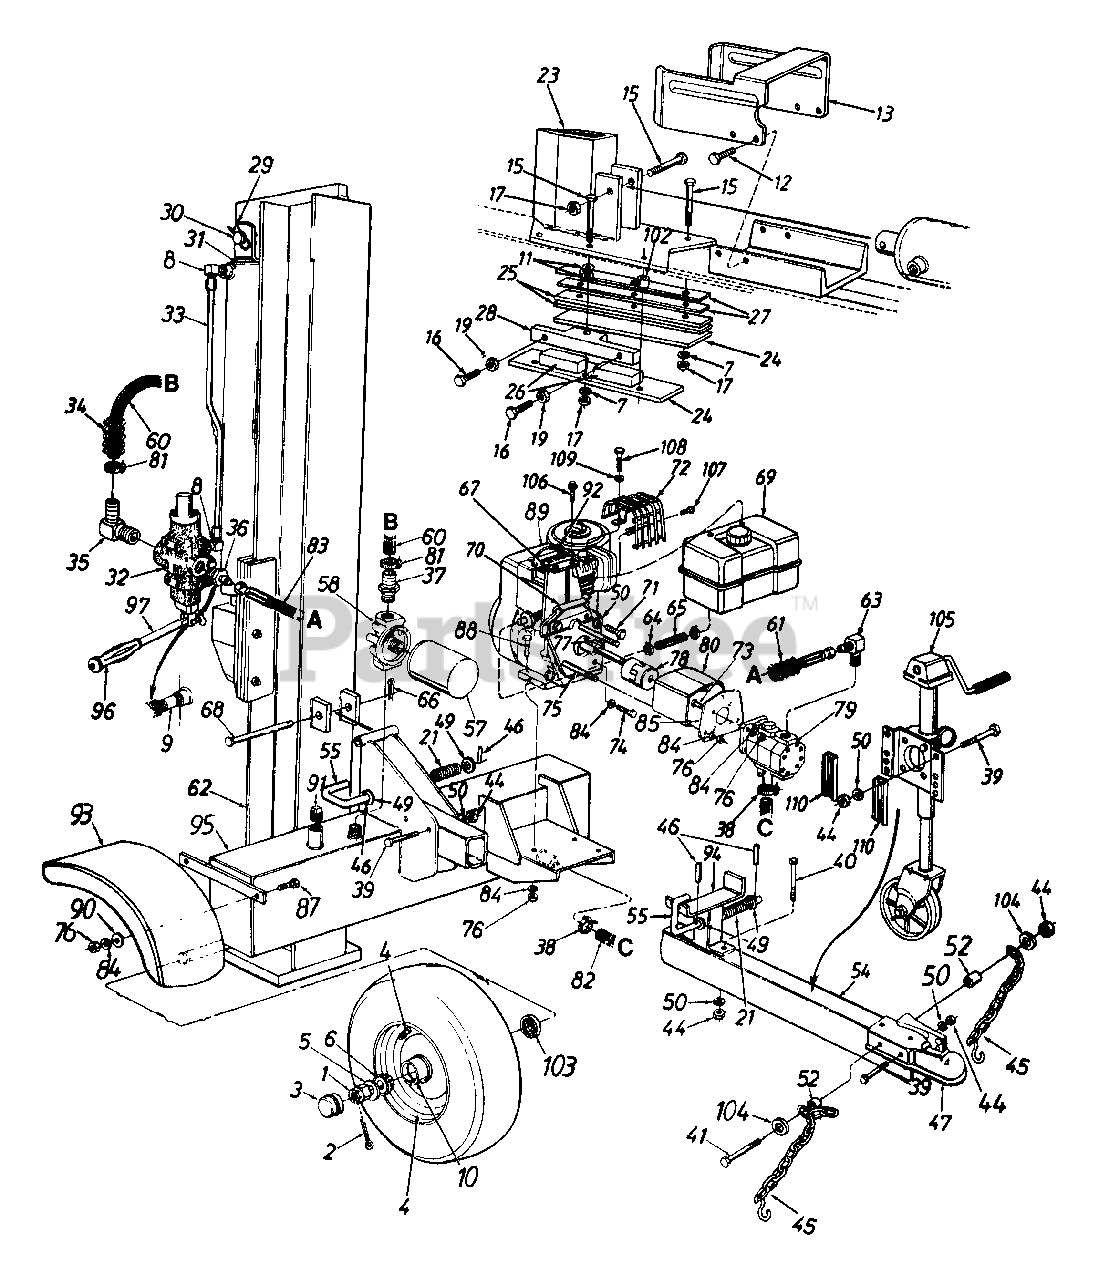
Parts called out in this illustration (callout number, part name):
1	Slotted Nut 3/4-16 Thd.
2	Cotter Pin 5/32" Dia.
5	FI-Wash..76" I.D. x 1.5" O.D.
6	Bearing Cone
7	L-Wash. 1/2" I.D.
8	90 Deg. Solid Male Adapter
9	Pipe Nipple 1/2 NPT
10	Bearing Cup
11	FI-Wash..531" I.D. x .94" O.D.
12	Hex Cap Scr. 3/8-16 x 1" Lg.
15	Hex Bolt 1/2-20 x 2.75" Lg. (Grade 8)
16	Hex Bolt 3/8-24 x 1.5" Lg.
17	Hex L-Nut 1/2-20 Thd.
19	Hex Jam Nut 3/8-24 Thd. (Grade 5)
21	Comp. Spring 4" Lg.
26	Adjustable Gib
29	External Cotter Pin
30	Cylinder Mounting Pin
33	Metal Pressure Tube
34	Hose Guard
35	Return Elbow
37	3/4" Hose Barb.
38	Hose Clamp 1.5" O.D.
39	Hex Bolt 3/8-16 x 3" Lg. (Grade 8)
40	Hex Bolt 3/8-16 x 4.75" Lg.
41	Hex Bolt 3/8-16 x 4.25" Lg.
44	Hex Nut 3/8-16 Thd.
45	Chain - Tow Hitch
47	Hitch Coupler
49	FI-Wash..635" I.D. x .93" O.D.
50	L-Wash. 3/8" I.D.
52	Spacer .445" Lg.
57	Filter Element
58	Filter Head
60	Return Hose 3/4" I.D. x 44" Lg.
61	Hose Guard
64	Hose Clamp .37" Dia.
65	Fuel Line (6" Lg.)
66	Cotter Pin 1/8" Dia.
67	Tank Mtg. Brkt.
68	Hinge Pin 1/2 x 4.8" Lg.
69	Fuel Tank Ass'y.
70	Support Brkt.
71	Hex Bolt 3/8-16 x 1" Lg.
72	Muffler Guard
73	Hex Bolt 5/16-24 x 1" Lg.
74	Hex Bolt 5/16-24 x .62" Lg.
75	Hex Bolt 5/16-24 x 5.25" Lg.
76	Hex Nut 5/16-24 Thd.
78	Flexible Coupling
79	Gear Pump
80	Coupling Shield
81	Hose Clamp 5/8"
82	Suction Hose 1" I.D.
83	High Pressure Hydraulic Hose 48"
84	L-Wash 5/16" I.D.
87	Hex Bolt 5/16-24 x .75" Lg.
88	Hex Bolt 5/16-24 x 1.75" Lg.
89	Engine
90	FI-Wash .344" I.D. x .875" O.D.
91	L-Vent Pipe Plug
92	Spark Plug Boot
97	Control Handle
102	Spacer 1/2" I.D. x .86" Lg.
103	Bearing Seal Only
104	Fl-Wash 3/8" I.D. x.87" O.D.
105	Jack Stand
106	Hex AB-Tap Scr. 1/4 x 3/4" Lg.
107	Hex Wash. Hd. Scr. #8 x .5" Lg.
108	Hex Bolt 1/4-20 x .5" Lg.
109	FI-Wash .25" I.D. x .5" O.D.
